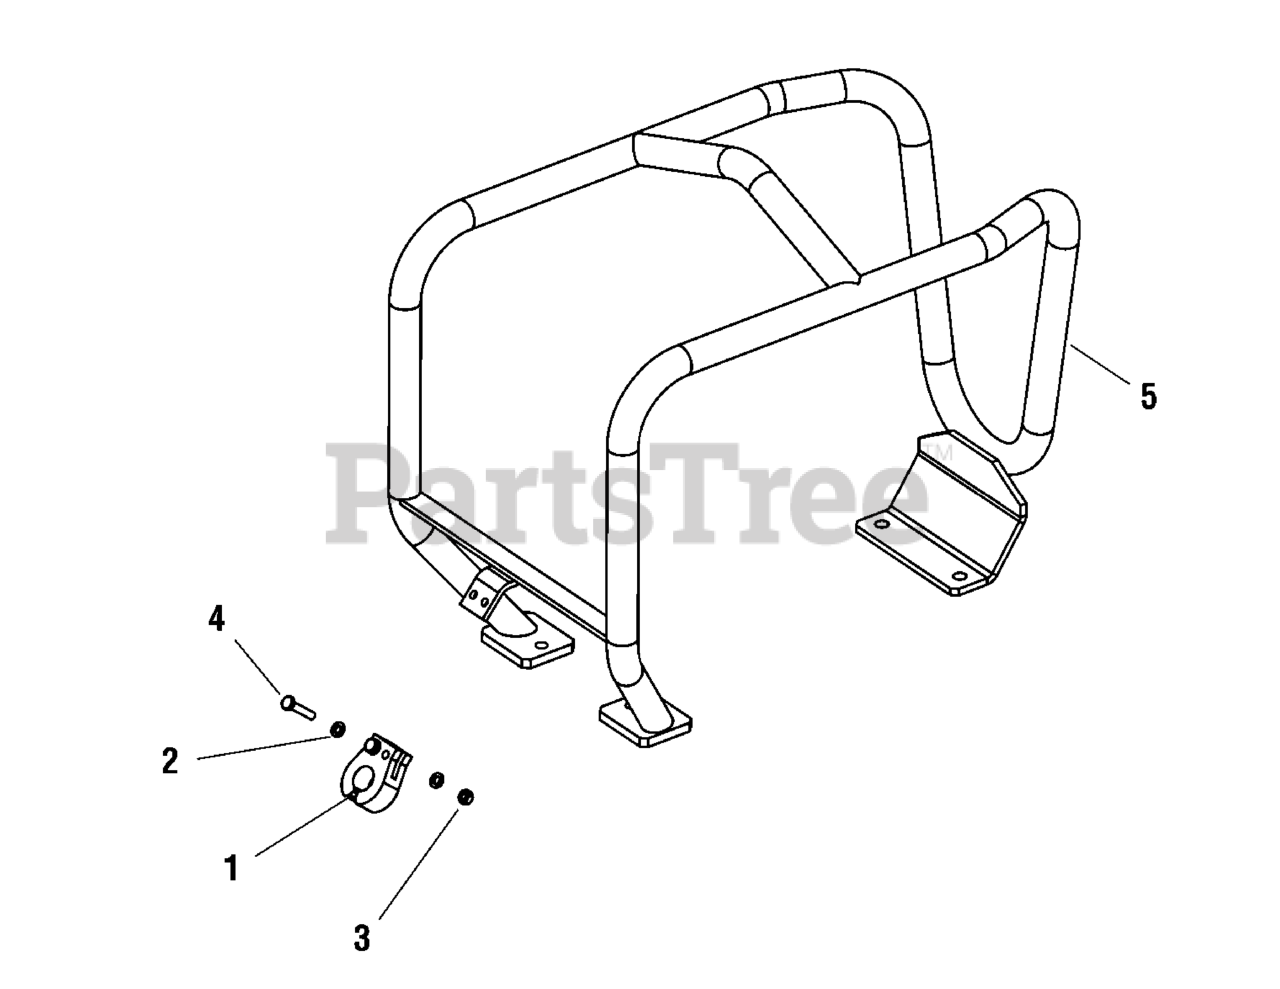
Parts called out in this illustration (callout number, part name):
1	CLIP, Rubber
2	WASHER, flat
3	NUT, Hex, M6
4	BOLT, Hex, M6 x 30
5	GUARD HOOK
